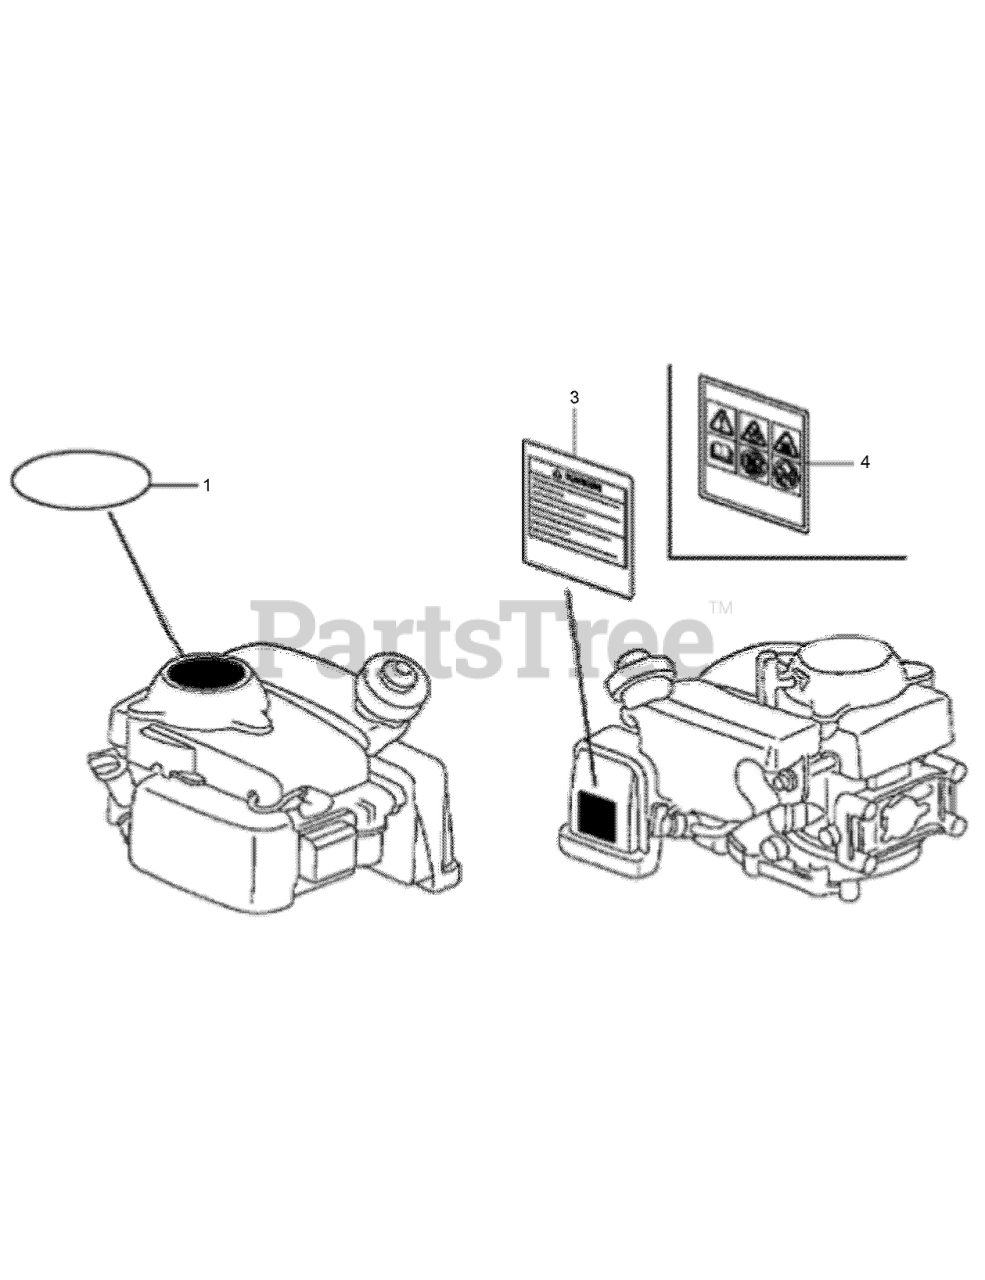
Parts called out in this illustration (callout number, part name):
1	EMBLEM
3	MARK-OPERATOR CAUTION (ENGLISH)
3	MARK-OPERATOR CAUTION (FRENCH)
4	MARK-OPERATOR CAUTION
